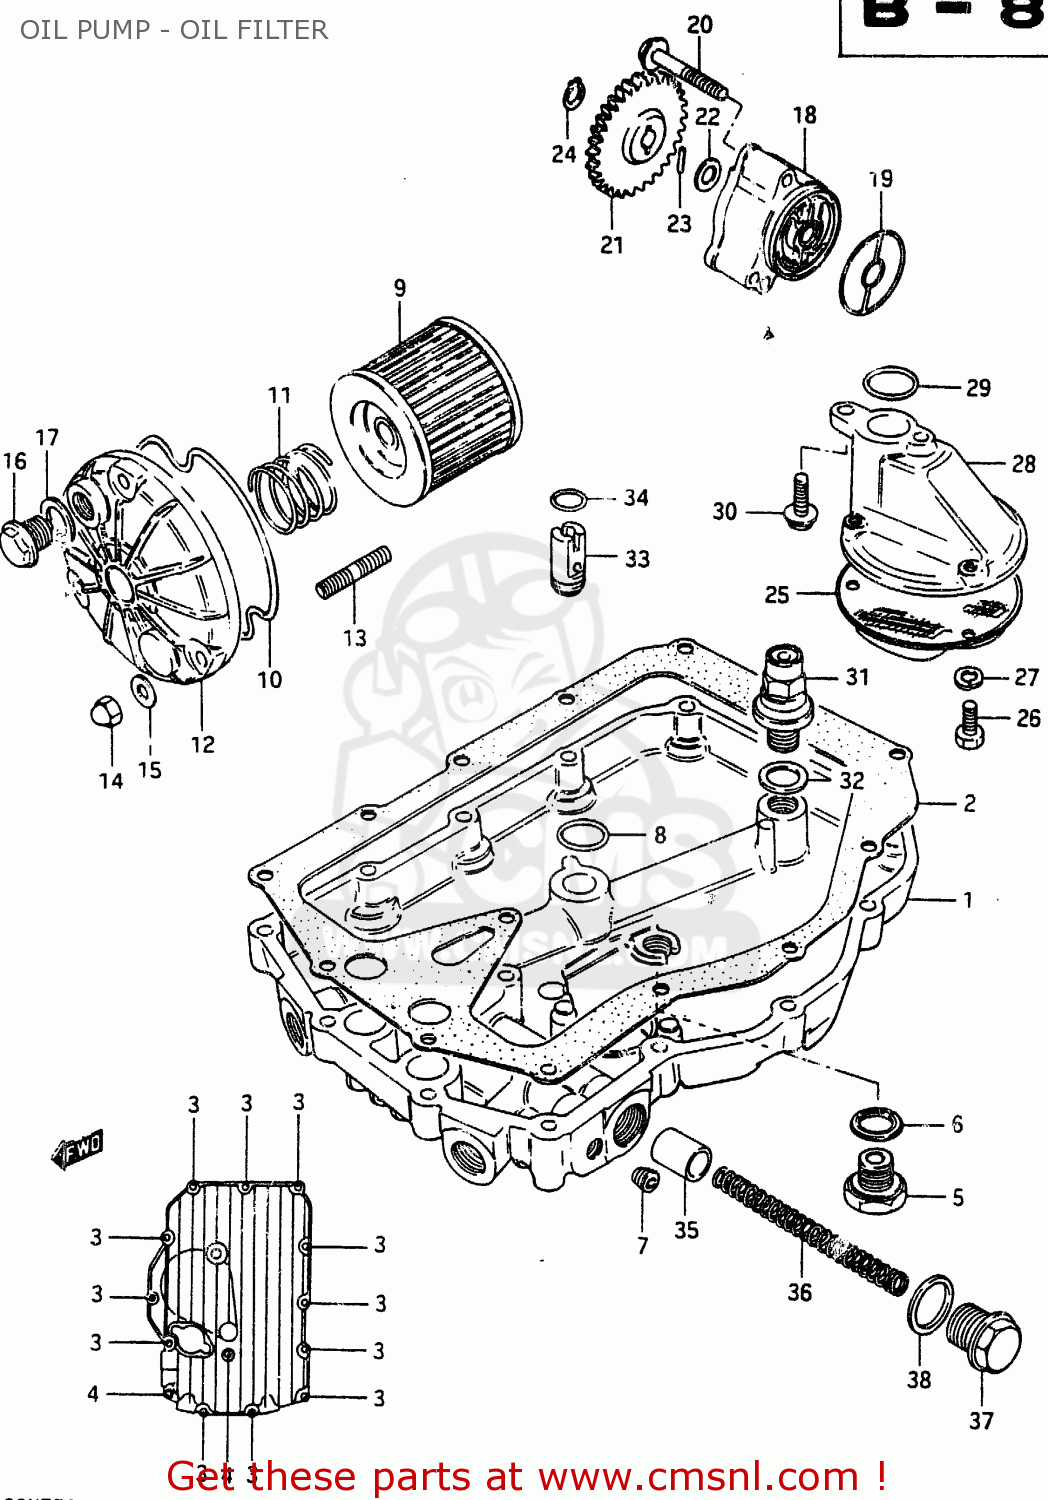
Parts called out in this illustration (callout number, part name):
1	PAN,OIL
2	GASKET,OIL PAN (MCA)
3	BOLT 6X30
4	BOLT
5	PLUG
6	GASKET(14X19.2X2) (NAS)
7	PLUG
8	O RING(D:3.2,ID:15.8)
9	FILTER ASSY,ENGINE OIL
10	O RING,OIL FILTER CHAMBER CAP
11	SPRING
12	CAP,OIL FILTER
13	STUD 6X20
14	NUT 6MM
15	WASHER
16	PLUG(14X12)
17	GASKET(14X19.2X2) (NAS)
18	PUMP ASSEMBLY,OIL
19	O-RING,OIL PUMP
20	BOLT
21	GEAR,OIL PUMP DRIVEN
22	SHIM
23	PIN(4X15.8)
24	CIRCLIP
25	STRAINER,ENGINE OIL
26	BOLT
27	LOCK WASHER
28	PROTECTOR,OIL STRAINER
29	O RING(D:3.2,ID:17.8)
30	BOLT,REAR
31	REGULATOR ASSY,ENGINE OIL
32	WASHER
33	VALVE ASSEMBLY,PISTON OIL
34	O RING(D:1.3,ID:9.8)
35	PLUNGER,OIL CONTROLL
36	SPRING
37	PLUG
38	O RING(D:2.4,ID:16.8)
